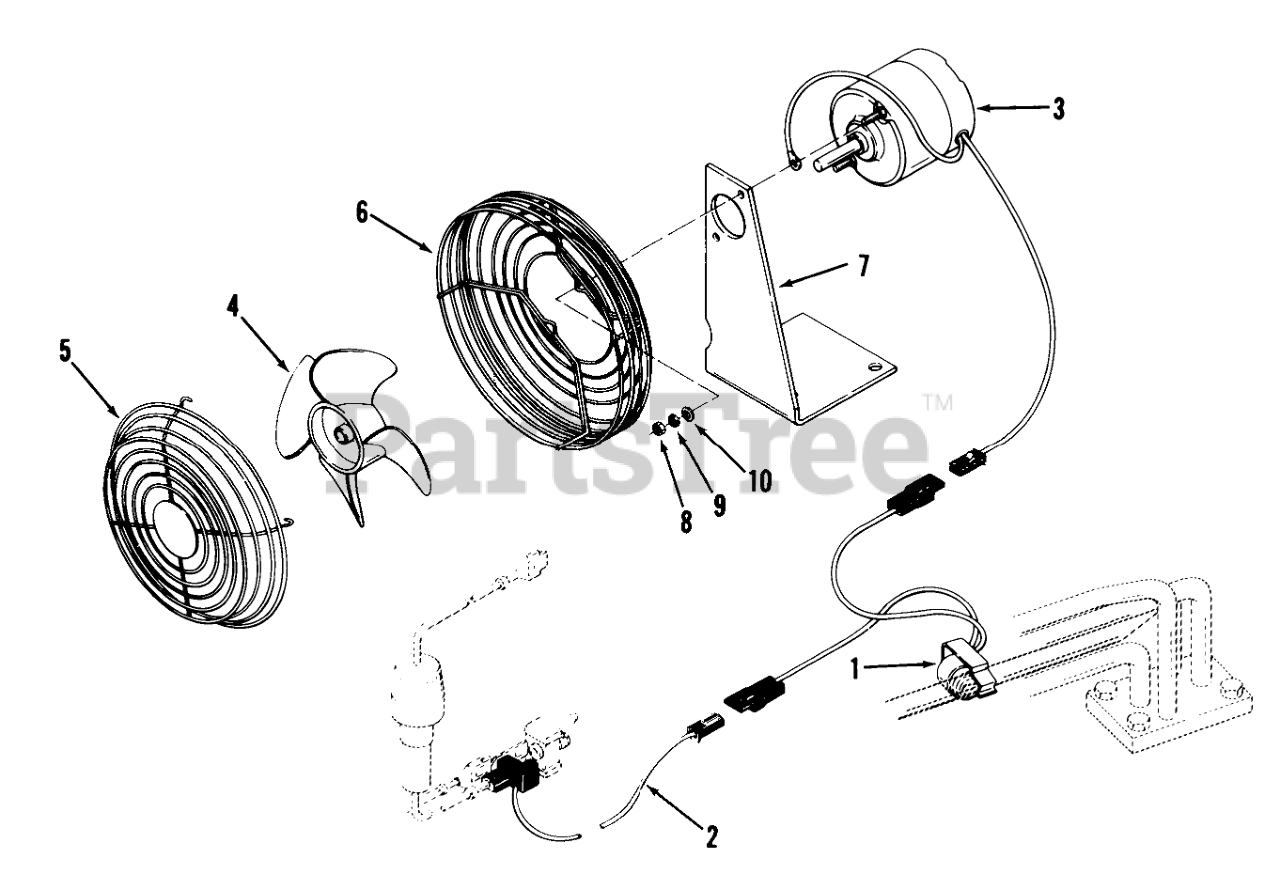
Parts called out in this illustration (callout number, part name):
1	THERMOSTAT
3	Motor
4	BLADE-FAN
5	Fan Guard-Front
6	Fan Guard-Rear
7	Fan Bracket
8	Nut #8-32
9	LOCKWASHER
10	WASHER
